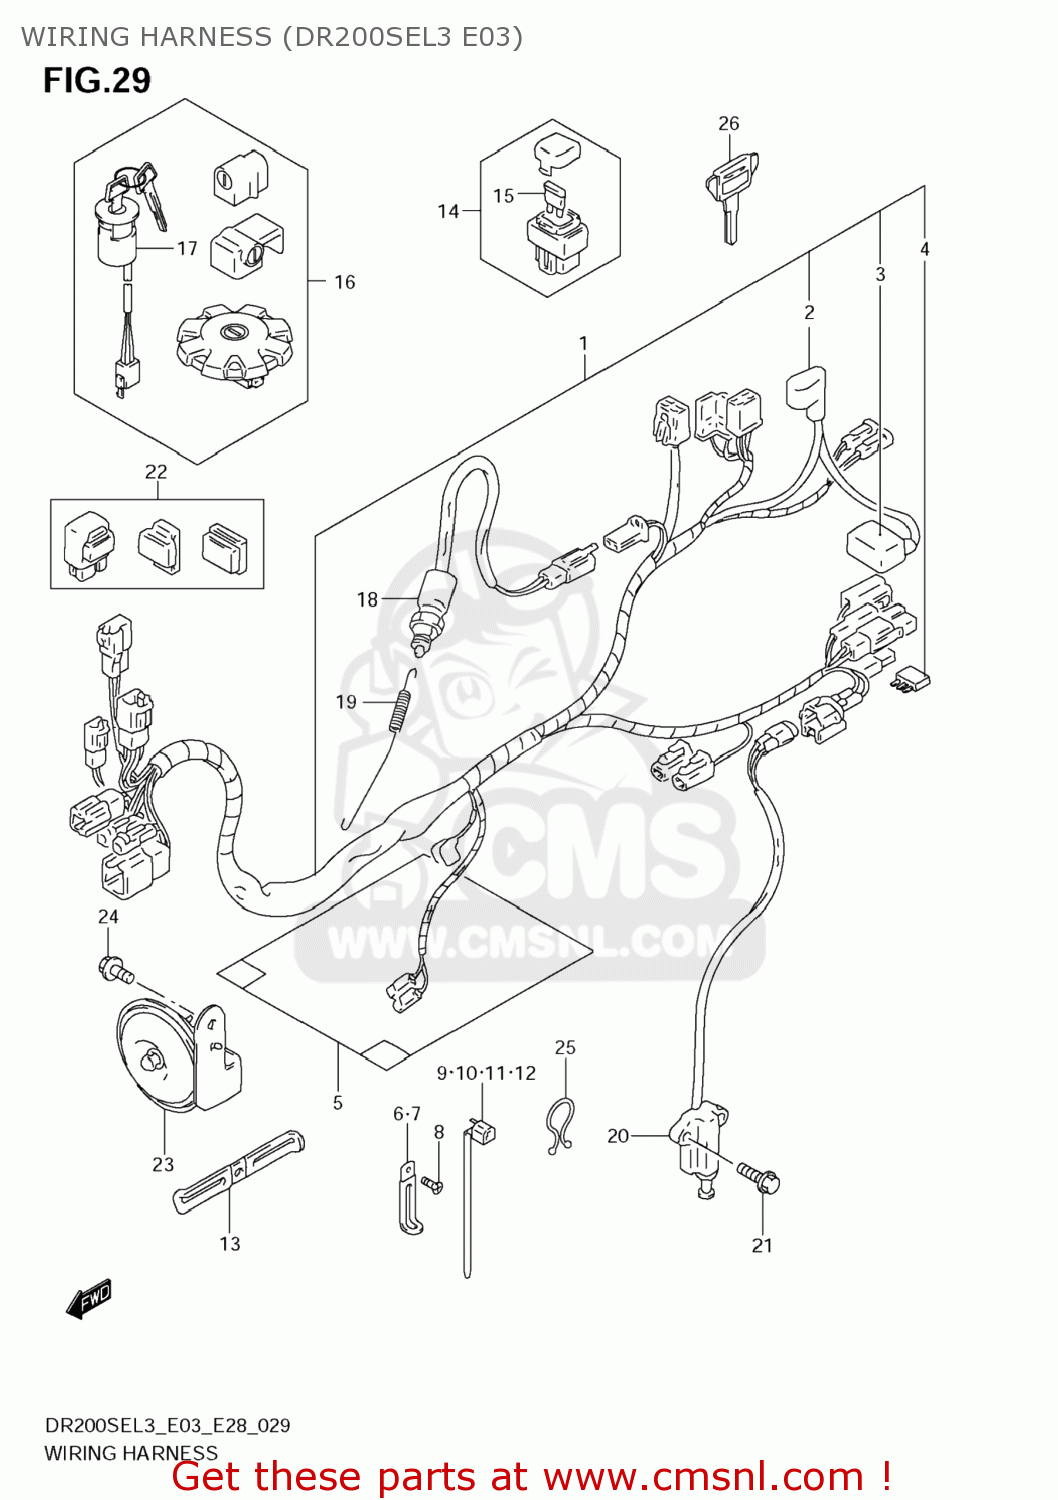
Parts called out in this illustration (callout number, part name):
1	HARNESS,WIRING
2	CAP,STARTER RELAY
3	CAP,BATTERY PLUS
4	DIODE(STANLEY DE8804)
5	COVER,WIRING HARNESS
6	CLAMP(L:45)
7	CLAMP(L:80)
8	SCREW
9	CLAMP(L:95)
10	CLAMP(L:125)
11	CLAMP(L:165)
12	CLAMP(L:235)
13	CLAMP,STARTER MOTOR LEAD
14	BOX ASSY,FUSE
15	FUSE(20A)
16	LOCK SET
17	SWITCH ASSY,IGNITION
18	SWITCH ASSY,STOP LAMP
19	SPRING
20	SWITCH ASSY,SIDE STAND
21	BOLT
22	RELAY ASSY
23	HORN ASSY
24	BOLT
25	CLIP(ID:11.5)
26	KEY,BLANK(TYPE:C)
